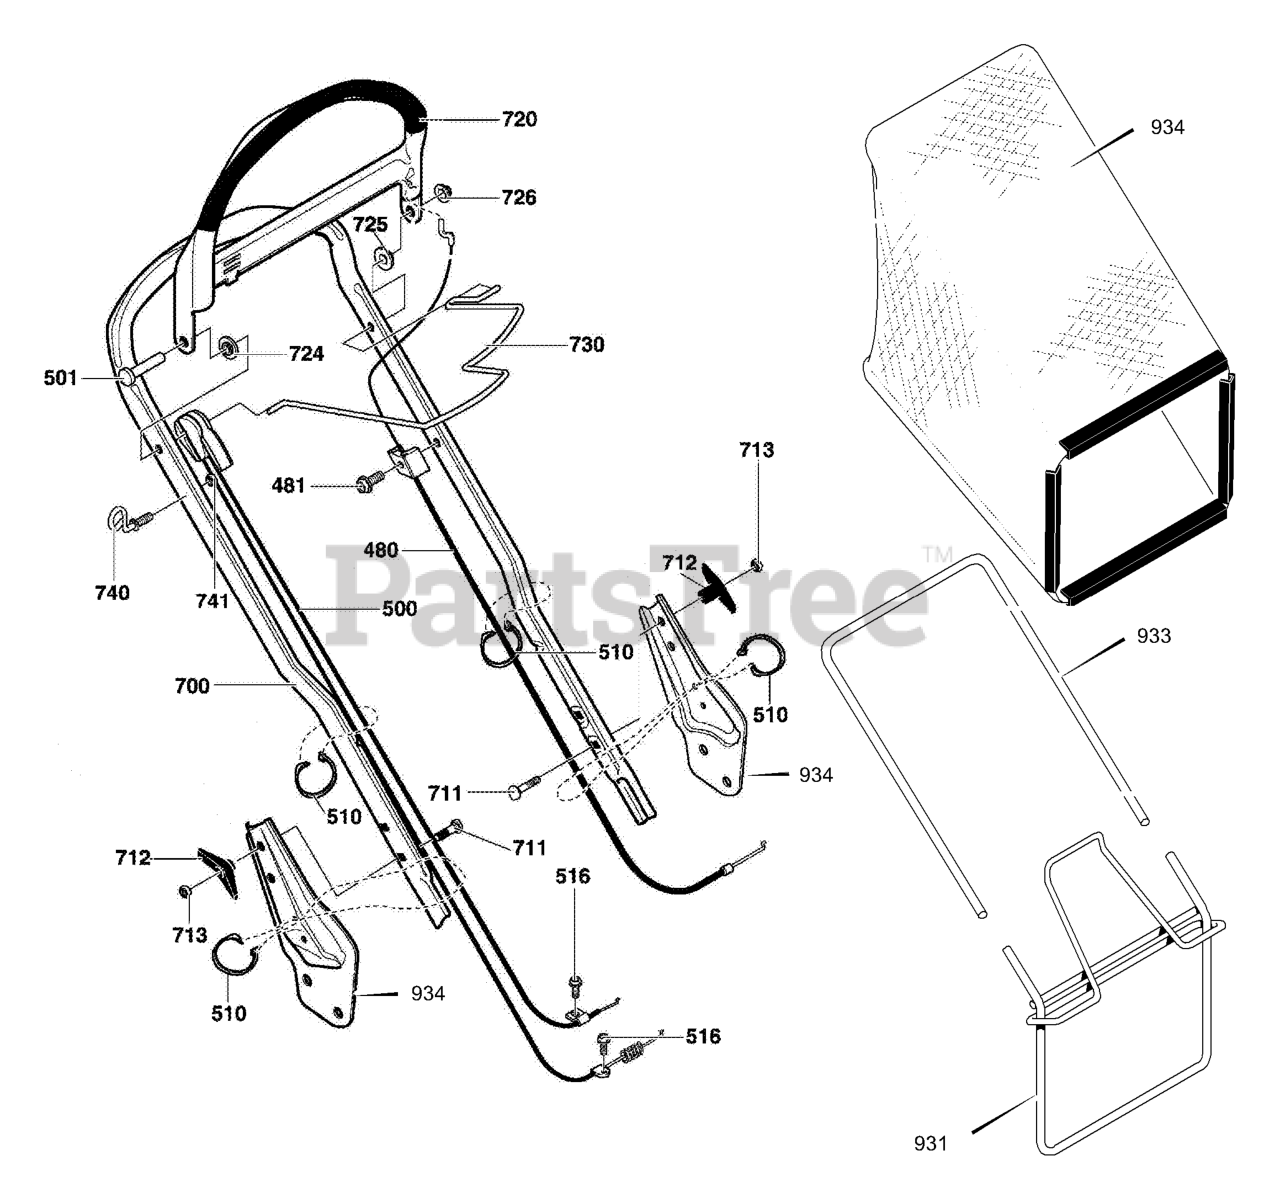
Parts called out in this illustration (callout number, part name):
80-20	BRKT., HANDLE RH
80-30	BRKT., HANDLE LH
480	CABLE,STOP
500	CABLE, DRIVE
510	TIE, CABLE
700	HANDLE
712	KNOB, T
720	LEVER, STOP
726	RETAINER
730	LEVER, DRIVE WIRE
740	GUIDE, ROPE
931	FRAME, BAGGER
933	SUPPORT, BAG
